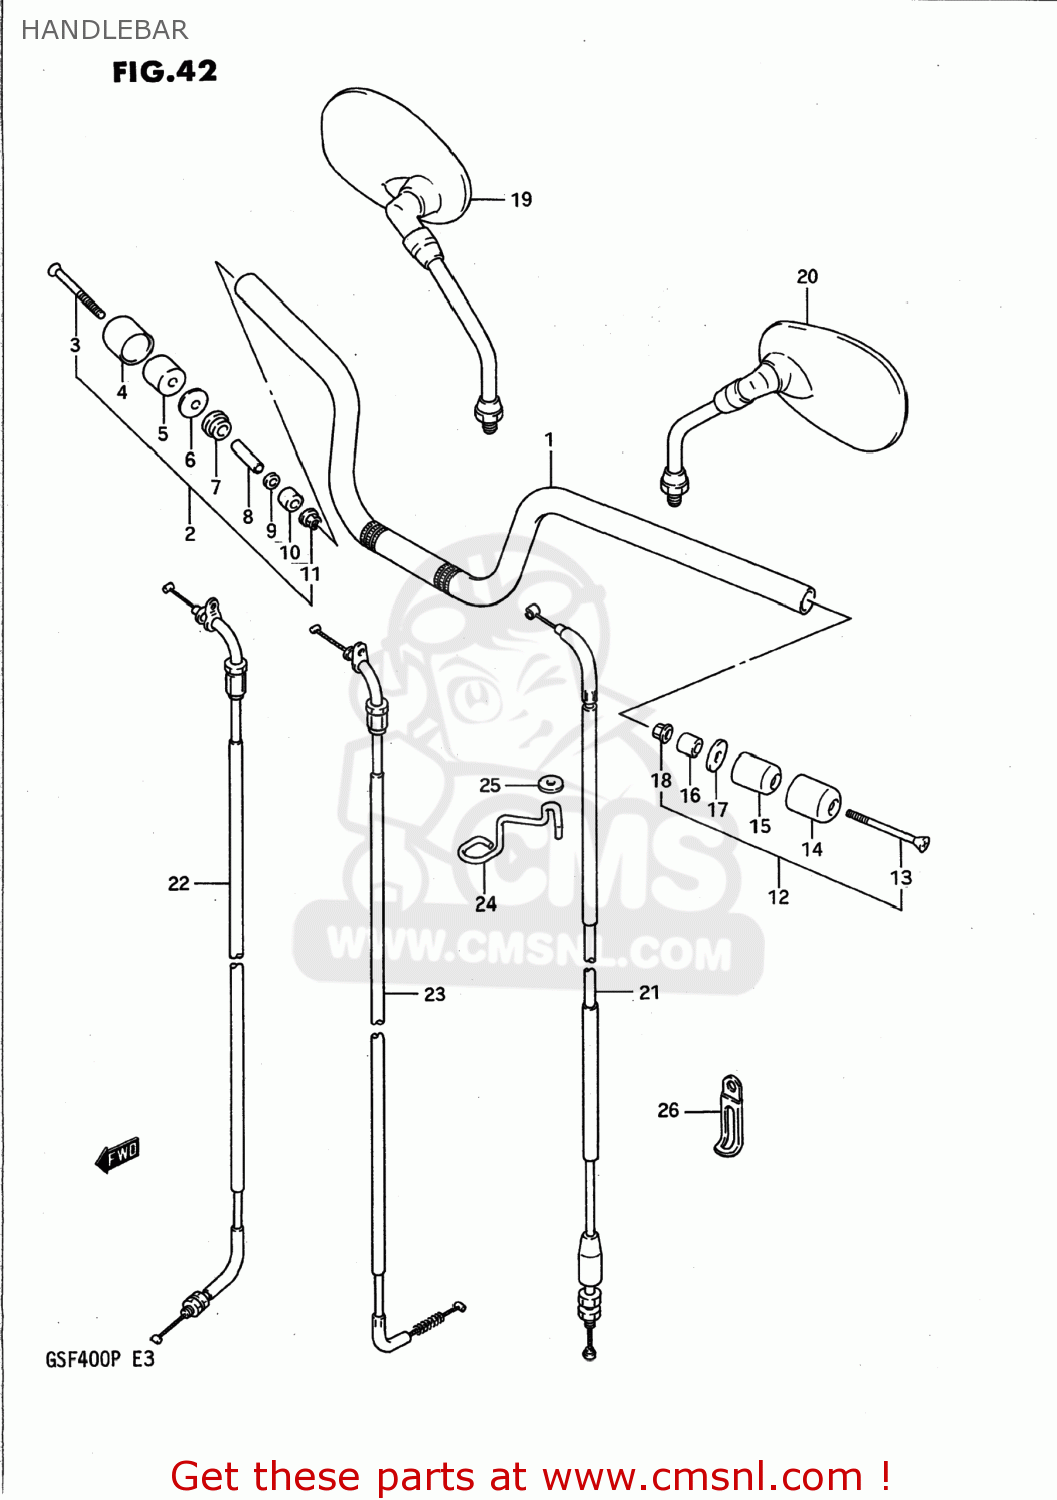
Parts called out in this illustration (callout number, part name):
1	HANDLEBAR,RIGHT
2	BALANCER SET,HANDLEBAR
3	SCREW(6X127)
4	CAP,BALANCER
5	BALANCER,HANDLEBAR
6	SPACER,BALANCER
7	EXPANDER,HANDLE BALANCER
8	SPACER,EXPANDER
9	WASHER
10	EXPANDER,HANDLE BALANCER
11	NUT
12	BALANCER SET,HANDLEBAR
13	SCREW
14	CAP,BALANCER
15	BALANCER,HANDLE
16	EXPANDER,HANDLE BALANCER
17	SPACER,BALANCER
18	NUT
19	MIRROR ASSEMBLY,REAR VIEW
20	MIRROR ASSEMBLY,REAR VIEW
21	CABLE ASSY,CLUTCH
22	CABLE ASSY,THROTTLE
23	CABLE,STARTER
24	GUIDE,CLUTCH CABLE
25	WASHER (6.5X20X1.6)
26	CLAMP
